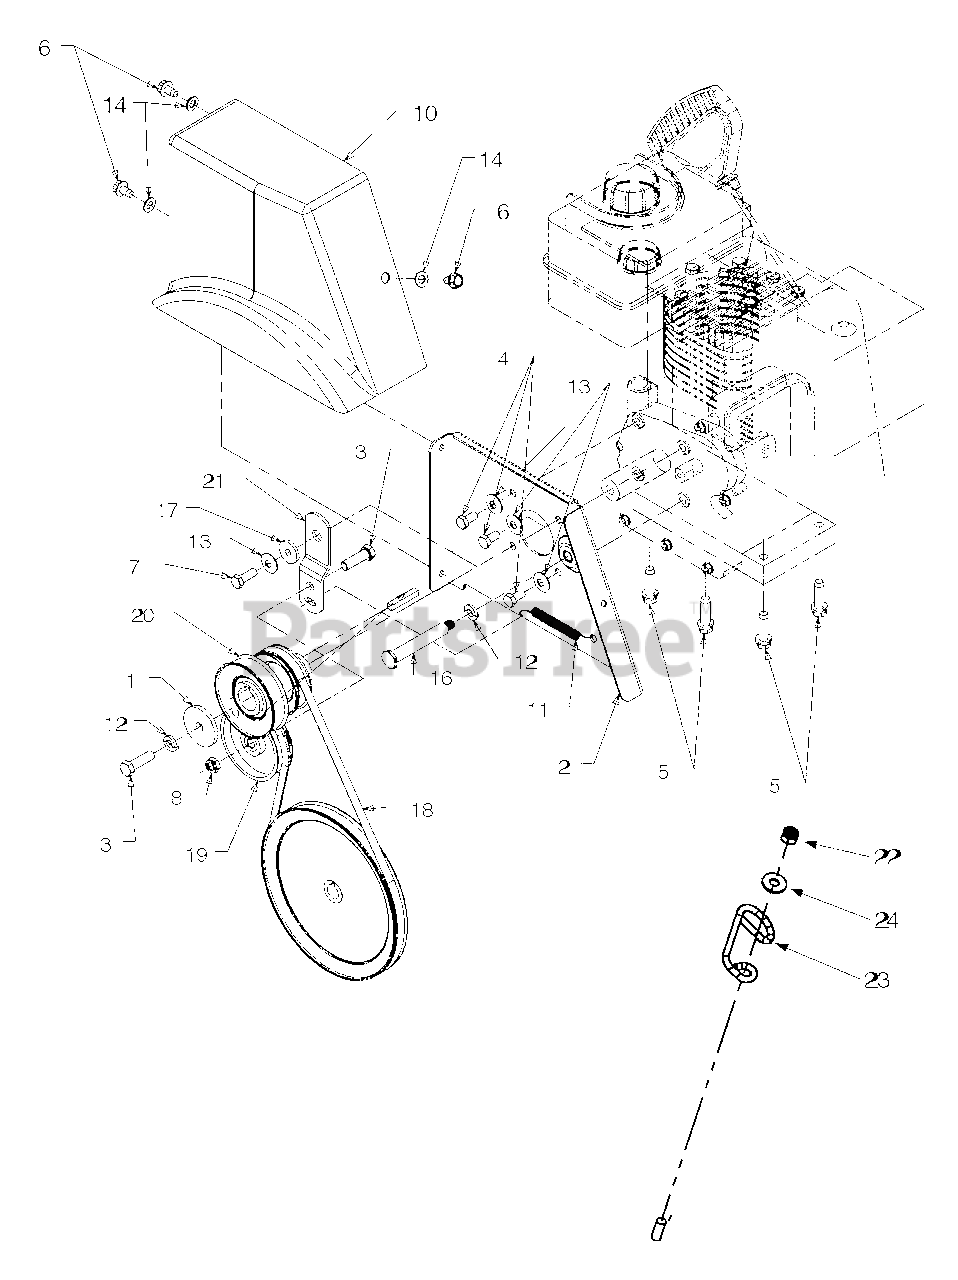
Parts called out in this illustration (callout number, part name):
1	Wash:.390 ID x 1.75 O.D.
4	Hex Hd. Screw 5/16-4 x .625 (Gr.5)
5	Hex TT-Sems Screw 3/8-16 x 1.25
6	Hex TT-Tap Screw 5/16-18 Thd.
7	Hex Lock Screw 5/16-24 x .875
8	Jam Nut 3/8-24 Thd.
10	Cvr:Belt
11	Spring:Extension
12	L-Wash .3/8
13	Bell-wash. .340 I.D. x .872 O.D.
14	Washer:Flat
16	Shoulder Screw
17	Shoulder Spacer
18	V-Belt
19	Idler:Flat
20	Double Pulley
21	Idler:Brkt
22	Hex Lock Nut 1/4-20 Thd.
23	Cable Control Wire
24	Fl-Wash. .28 x .74 x .063
